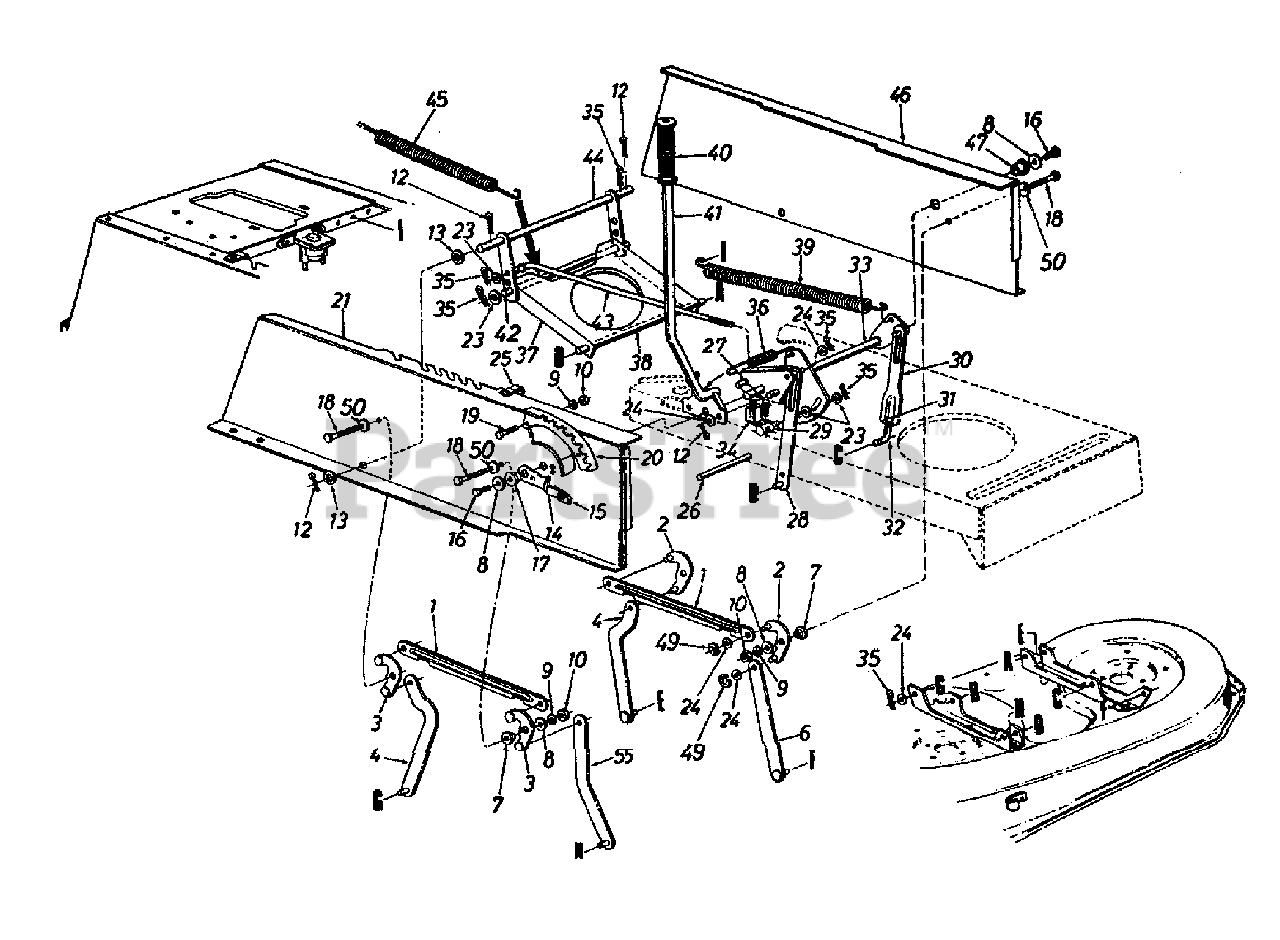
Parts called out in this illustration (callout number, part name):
3	Pivot Link Ass'y.-R.H.
7	Shld. Spacer .318" I.D.
8	Fl-Wash. .344" I.D. x .62" O.D.
9	L-Wash. 5/16" I.D.
10	Hex Nut 5/16-18 Thd. (Gr. 5)
12	Cotter Pin 1/8" Dia.
13	Fl-Wash. .635" I.D. x 1.0" O.D.
14	Height Adj. Stop Lever Ass'y.
15	Knob
16	Hex Wash. TT-Tap Scr.5/16-18 x .75" Lg.
17	Flange Brg. .63" I.D.
18	Hex Wash. Hd. Scr. 5/16-18x .875"
19	Hex Bolt 5/16-18 x .75" Lg.
20	Index Brkt.
24	Fl-Wash. .531" I.D. x .93" O.D.
25	Clamp
26	Running Board Rod
27	Hex Wash. Hd. Tap Scr.
31	Hex Nut 1/2-20 Thd. (Gr. 5)
32	Lift Link Adjuster
35	Inter. Cotter Pin 3/8" Dia.
36	Extension Spring
39	Extension Spring
40	Grip (Lift Handle)
43	Disengagement Rod
49	"E"-Ring
50	Bell-Wash. .325" I.D.
